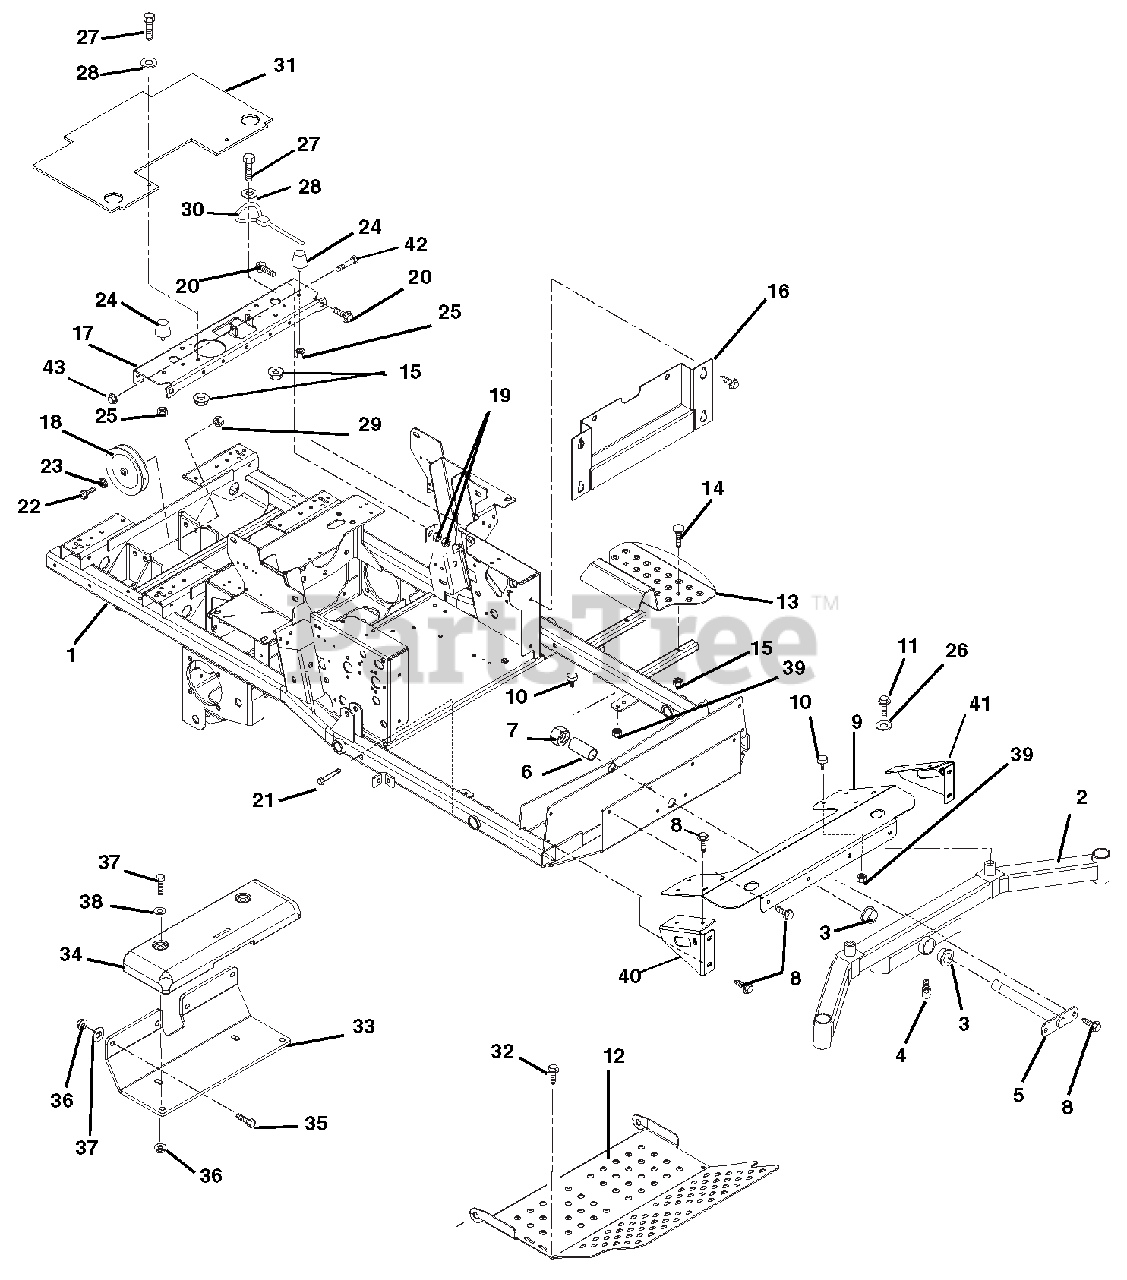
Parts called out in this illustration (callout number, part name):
1	WLDMT, FRAME
2	WMT, FRONT AXLE
3	BSHG-FLG1.020X1.385X.75X1.75NY
4	FTG,LUBE 45 DEG
5	PIN - AXLE
6	SPACER 1.009 X 1.250 X 4.23
7	NUT-LK-NYL 1.0-14 YWZC
8	@SCR-TAP .38-16X.75 HWH TR YWZ
9	COVER - AXLE
10	BUMPER, RUBBER
11	BLT-HEX .50-20X1.00 GR5 YWZC
12	PANEL, INSPECTION
13	STEP, INGRESS (BLACK)
14	@BLT-RDHDSQNK .31-18X1.75 G5YZ
15	@NUT-LK-TOP-FLG .31-18 YWZC
16	PLATE - KICK
17	BRACE, SEAT CROSS WITH LATCH
18	PLY-V 6.0 X .500 ID DBL BRG.
19	NUT-RTNR .375-16X.37
20	BLT-SERHFWH .375-16X1.0 YWZC
21	@BLT-HEX .50-13X3.25 GR5 YWZC
22	@BLT-HEX .50-13X2.25 GR5 YWZC
23	WSHR-FL-STL .505X.880X.072 YWZ
24	BUMPER, RUBBER CONE,STUD MOUNT
25	@NUT-SPNLK-FLG .312-18 YWZC
26	WSHR-FLT .640X1.75X.250 YWZC
27	@BLT-HEX .31-18X1.00 GR5 YWZC
28	WSHR-FL-STL .344X1.125X.135
29	@NUT-LK-TOP-FLG .50-13 YWZC
30	CABLE, SEAT PROP.
31	GUARD - GRASS
32	@SCR-TAP .38-16X1.00 HWH TR YZ
33	BRACKET - WEIGHT - 252
34	WEIGHT, CAST IRON
35	@BLT-HEX .50-13X1.00 GR5 YWZC
36	@NUT-LK-TOP-FLG .50-13 YWZC
37	@BLT-HEX .50-13X4.50 GR5 YWZC
38	@WSHR-FL-STL.531X1.06X.095YWZC
39	@NUT-SPNLK-FLG .312-18 YWZC
40	WMT - RH AXLE COVER SUPPORT
41	WMT - LH AXLE COVER SUPPORT
42	@BLT-HEX .38-16X3.00 GR5 YWZC
43	@NUT-LK-TOP-FLG .38-16 YWZC
